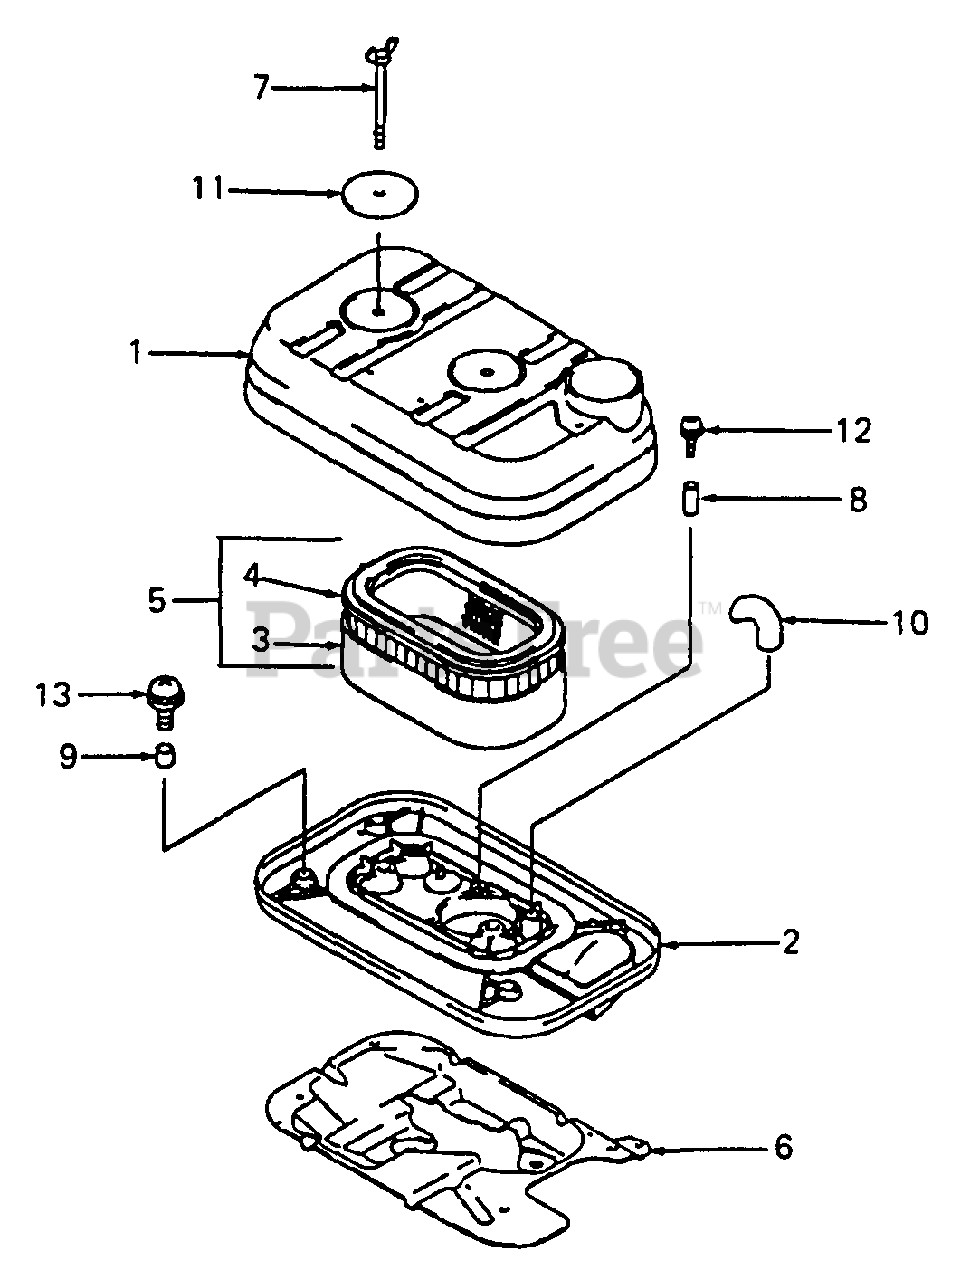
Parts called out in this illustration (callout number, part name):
1	Case, Air Filter
2	Base, Air Filter
3	Element, Foam
4	Element, Air Filter
5	Air Filter Assy
6	Bracket, Air Filter
8	Collar, 5.1 x 6.3 x 14
9	Collar, 6.2 x 7.8 x 7.5
11	Washer
12	Screw, Pan, WSP
